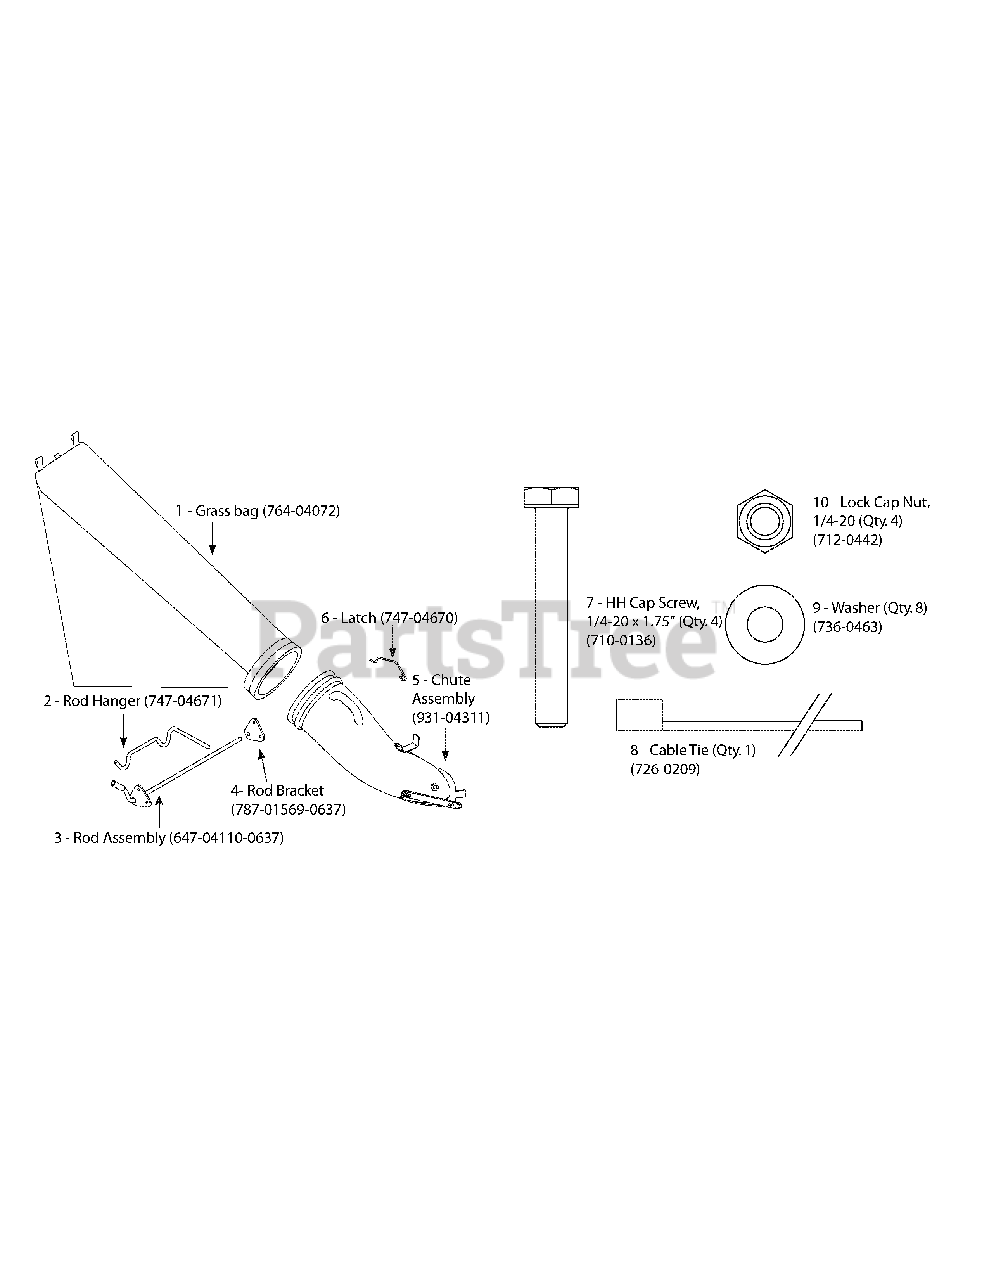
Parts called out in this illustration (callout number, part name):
1	Grass Bag - Sears Craftsman
2	Rod Hanger
3	Rod Assembly
4	Rod Bracket
5	Chute Assembly
7	Screw Hex 1/4-20 X 1.75
8	Tie Cable 29 3/4"
9	Washer
10	Nut, Hex Lock 1/4-20
